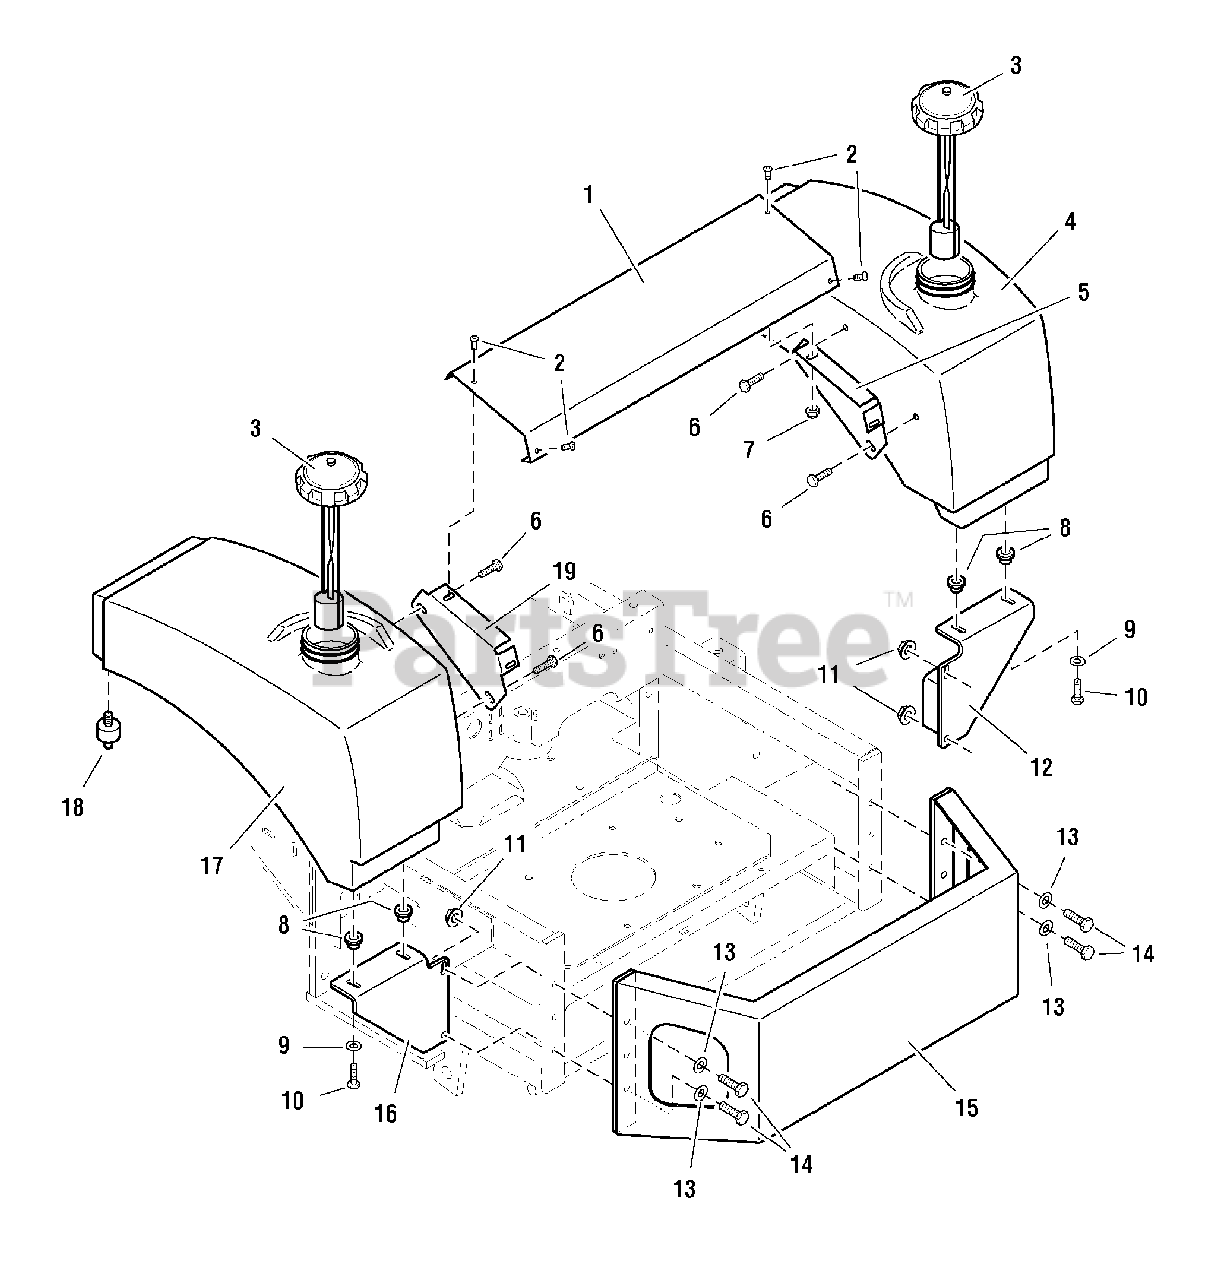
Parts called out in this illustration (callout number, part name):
1	FUEL TANK TIE BAR
2	SCREW, Allan Hd, 1/4-20 x 3/4
3	CAP, Fuel Tank
4	FUEL TANK-RH, Complete
5	TIE BAR MOUNT-RH
6	CAPSCREW, Hex Hd, 5/16-18 x 3/4
7	NUT, Hex, Nylon Lock, 1/4-20
8	RUBBER BUSHING
9	WASHER, 5/16
10	CAPSCREW, Hex Hd, 5/16-18 x 1-1/4
11	NUT, Hex, Serrated Flange, 3/8-16
12	TANK MOUNT-RH
13	WASHER, 3/8
14	CAPSCREW, Hex Hd, 3/8-16 x 1
16	TANK MOUNT-LH
17	FUEL TANK-LH, Complete
18	RUBBER ISOLATOR
19	TIE BAR MOUNT-LH
